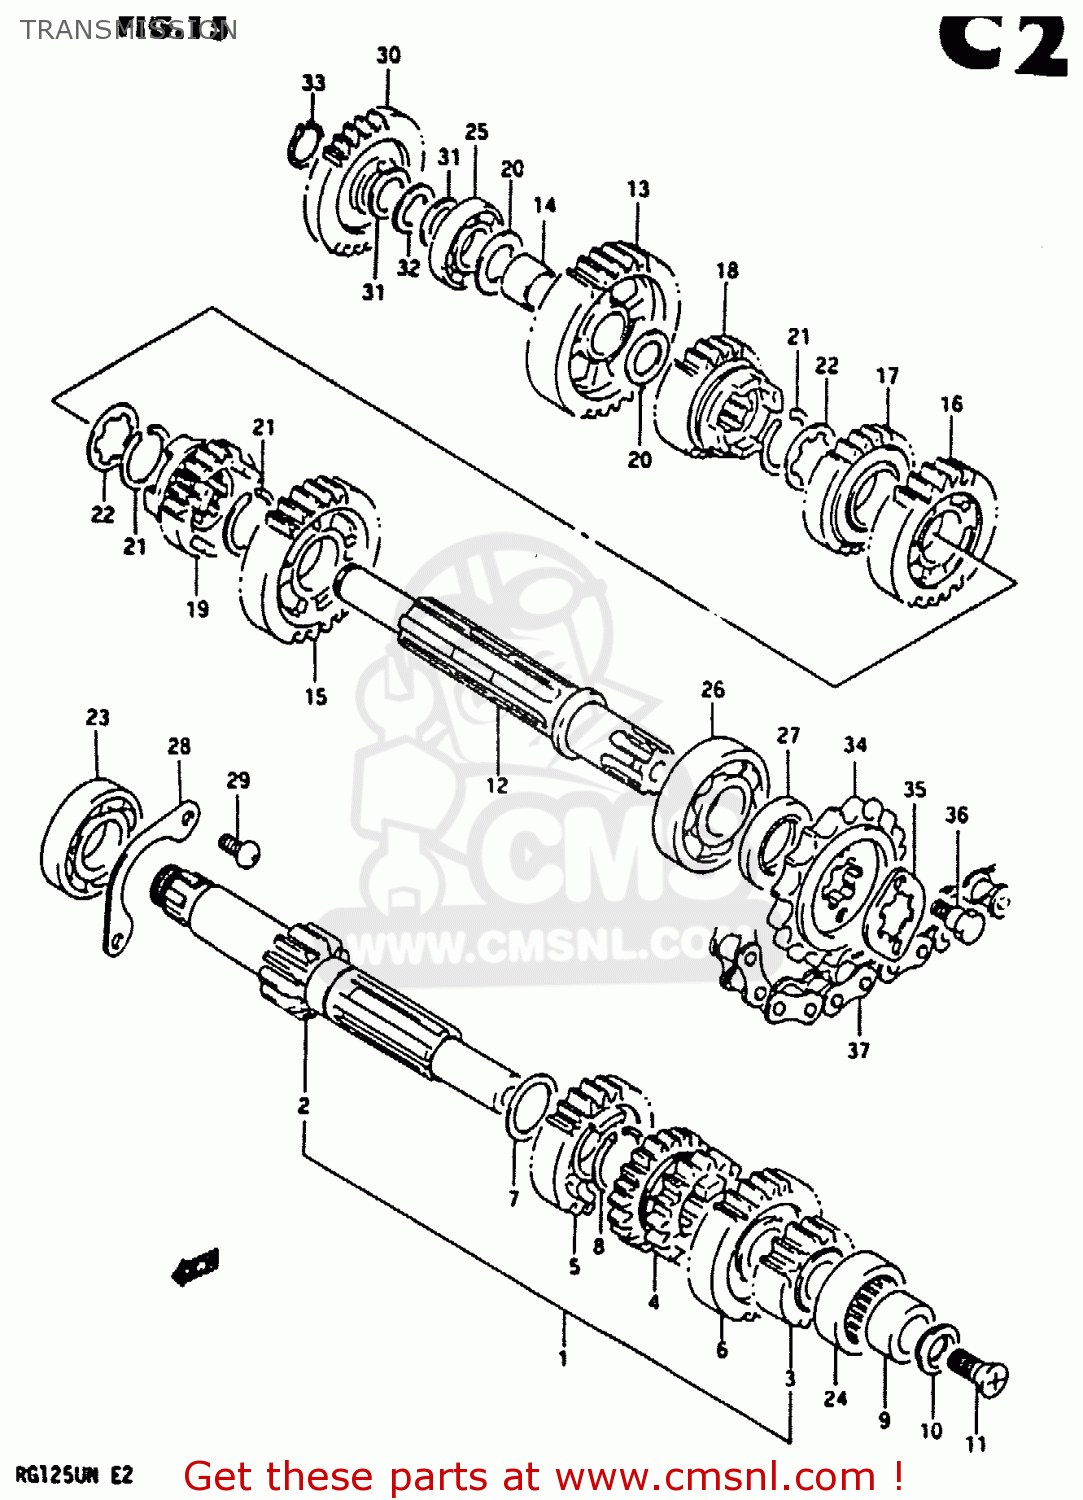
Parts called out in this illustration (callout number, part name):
1	COUNTER SHAFT
2	SHAFT,COUNTER(NT11)
3	GEAR,2ND DRIVE(NT:14)
4	GEAR, 3RD/4TH DRIVE (NT:15/21)
5	GEAR,5TH DRIVE(NT:24)
6	GEAR, 6TH DRIVE (NT:24)
7	WASHER
8	CIRCLIP
9	RACE,CNTR SHAFT L BRG INNER
10	RETAINER,CNTR SHAFT L BEARING
11	SCREW
12	SHAFT,DRIVE
13	GEAR, 1ST DRIVEN (NT:29)
14	BUSH(15X18X13)
15	GEAR,2ND DRIVEN(NT:26)
16	GEAR,3RD DRIVEN(NT:20)
17	GEAR,4TH DRIVEN(NT:23)
18	GEAR,5TH DRIVE
19	GEAR, 6TH DRIVEN (NT:20)
20	WASHER,THRUST
21	CIRCLIP
22	WASHER,LOCK
23	BEARING(20X47X10.5)
24	BEARING,20X32X1
25	BEARING(15X35X8)
26	BEARING(20X52X12.5)
27	OIL SEAL (20X35X5)
28	RETAINER,CNTR SHAFT BEARING
29	SCREW 6X12
30	GEAR,KICK STARTER IDLE
31	THRUST WASHER
32	WAVE WASHER
33	CIRCLIP
34	SPROCKET,ENGINE(NT:16)
35	PLATE
36	BOLT(6X13)
37	CHAIN ASSY, DRIVE (DID 428VCA*130LE)
